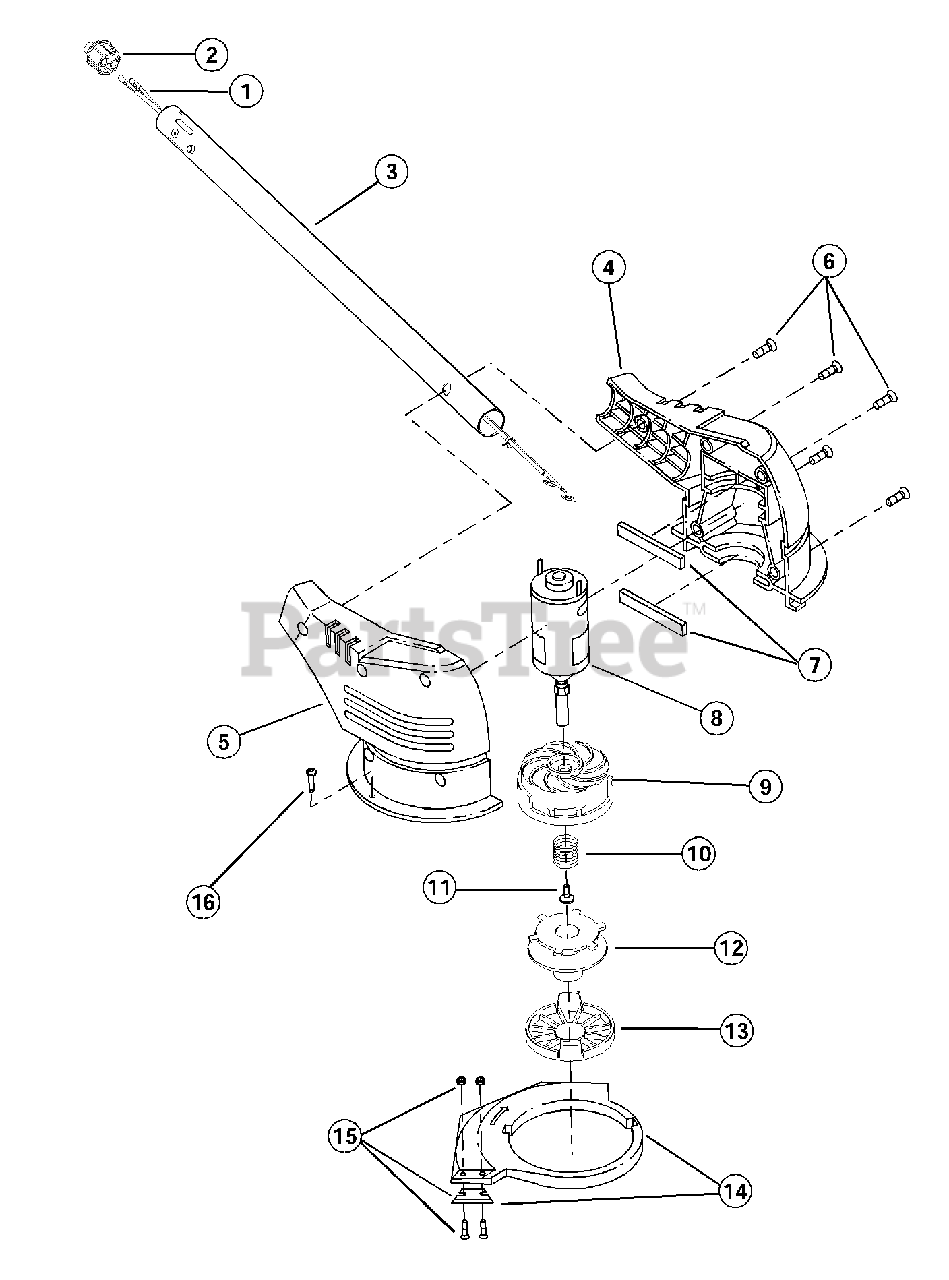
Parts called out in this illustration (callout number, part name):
1	Wiring Harness
2	Plug Connector
3	Lower Motor Wire Tube
4	Left Motor Housing
5	Right Motor Housing
6	Motor Housing Screw
8	Motor with Shaft
9	Outer Spool and Eyelet/Motor Fan
12	Inner Reel with .080" Line
13	Reel Cover
14	Guard and Blade Assembly
15	Blade Assembly
16	Guard Screw
